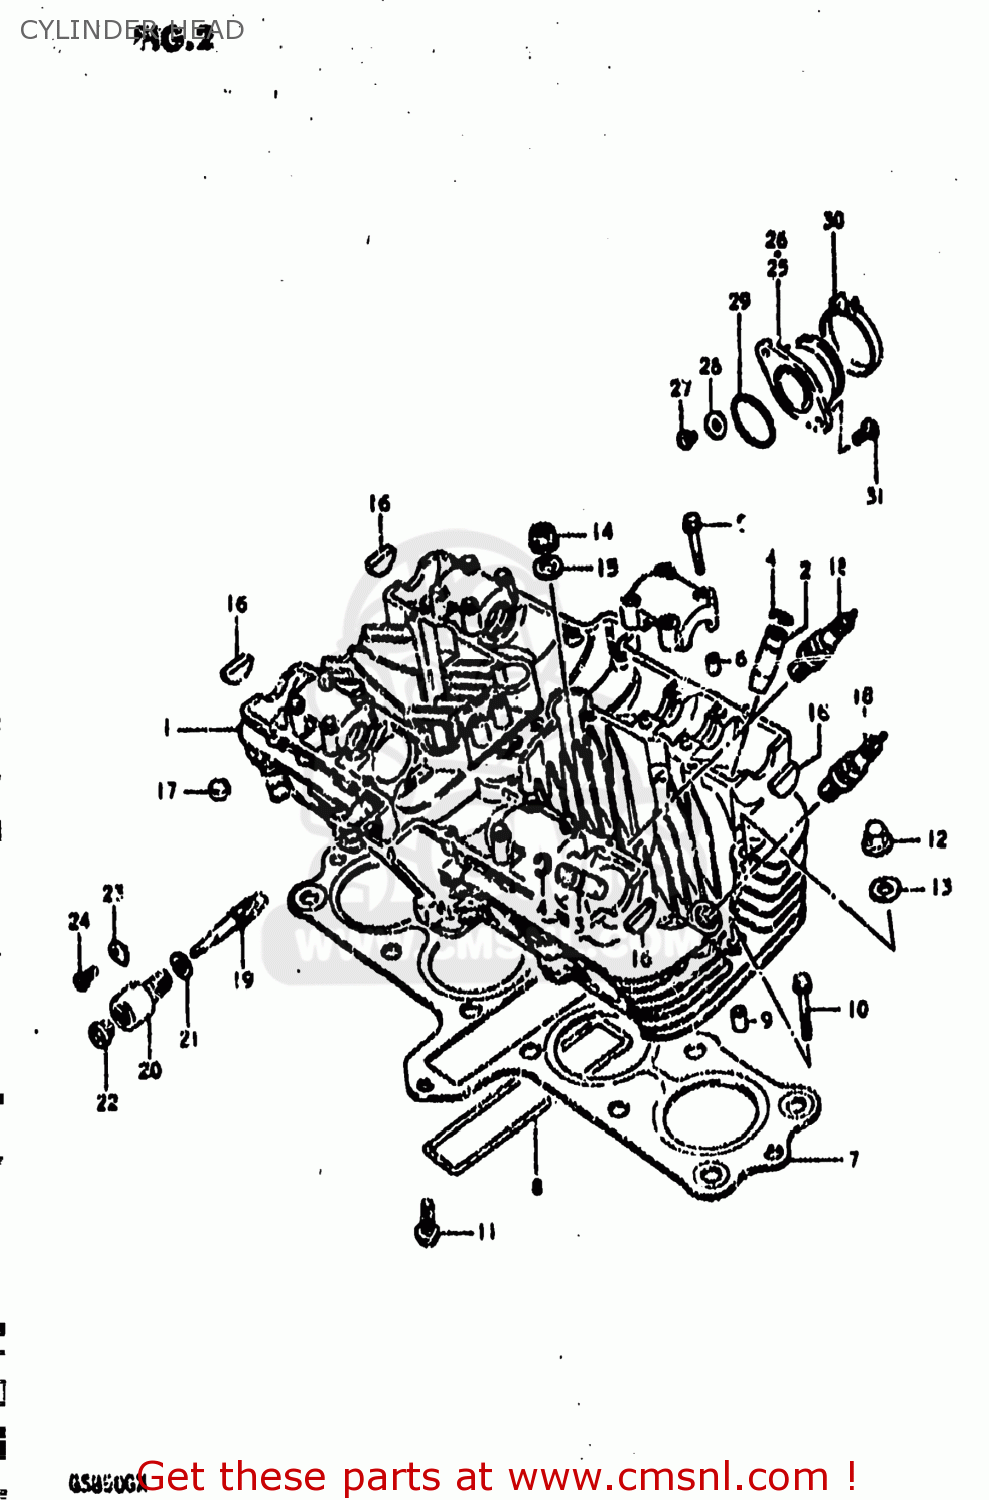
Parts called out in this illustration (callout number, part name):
1	HEAD ASSEMBLY,CYLINDER
2	GUIDE,INTAKE VALVE
3	GUIDE,EXHAUST VALVE
4	RING,SNAP
5	BOLT(6X39)
6	PIN(6.2X8X11)
7	GASKET,CYLINDER HEAD (MCA)
8	O RING(D:3,ID:26X157)
9	PIN
10	BOLT,UNDER
11	BOLT
12	NUT
13	GASKET (NAS)
14	NUT
15	WASHER(10.5X22X2.3)
16	PLUG
17	PAD
18	SPARK PLUG
19	GEAR,TACHOMETER DRIVEN
20	SLEEVE,TACHOMETER DRIVE
21	SEAL,TACHOMETER DRIVEN
22	SEAL,OIL(5X12X8)
23	PLATE,TACH DRIVE GEAR SLEEVE
24	SCREW(5X12)
25	PIPE,INTAKE,R
26	PIPE,INTAKE,L
27	BOLT
28	GASKET(5.3X9.3X1.2) (NAS)
29	O-RING
30	CLAMP
31	SCREW
